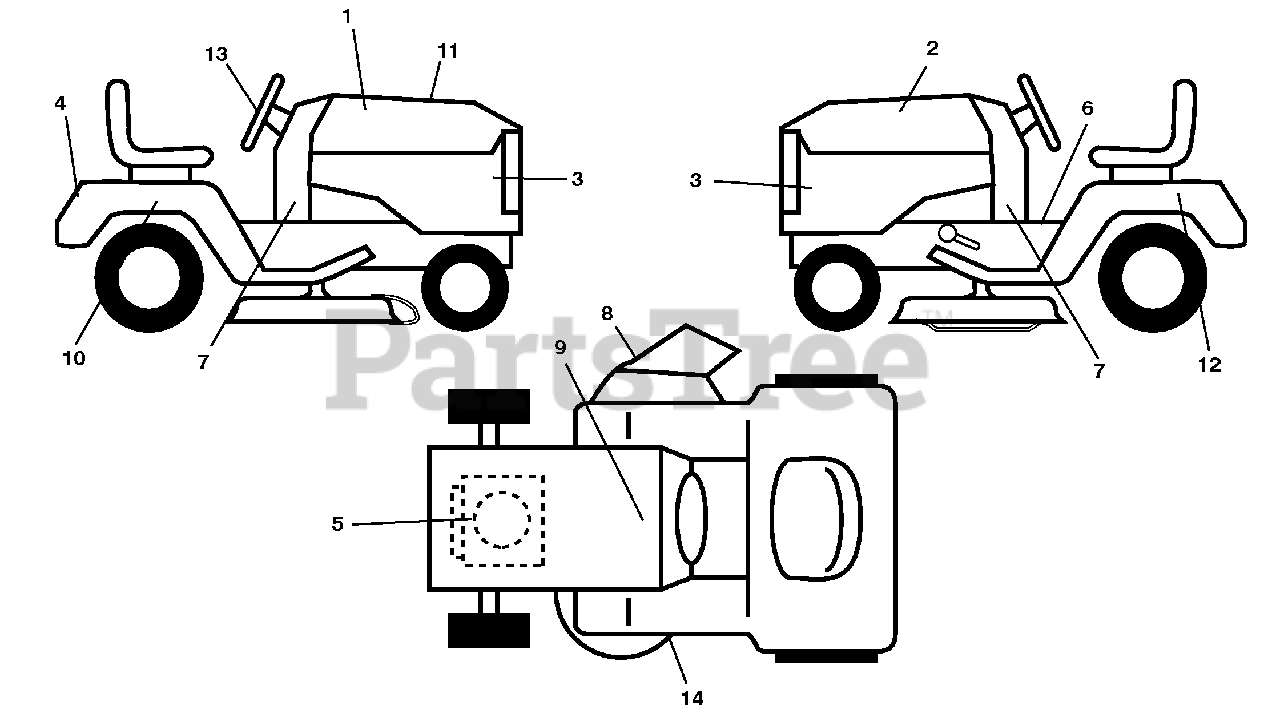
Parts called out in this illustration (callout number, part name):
1	Decal, Hood RH
2	Decal, Hood LH
3	Decal, Side Panel
4	Decal, Fender
5	Decal, Engine
6	Decal, Fender Operator's
7	Decal, Lower Dash
8	Decal, Warning
9	Decal, Battery Dnge/Poi
10	Decal, Fender Side RH
11	Decal, Replacement
12	Decal, Fender Side LH
13	Decal, Steering Wheel
14	Decal, Mower Schematic
14	Pad, Footrest, RH
14	Decal, Bypass
14	Pad, Footrest, LH
14	Manual, Operator's (Eng/French)
14	Manual, Parts (Eng/French)
